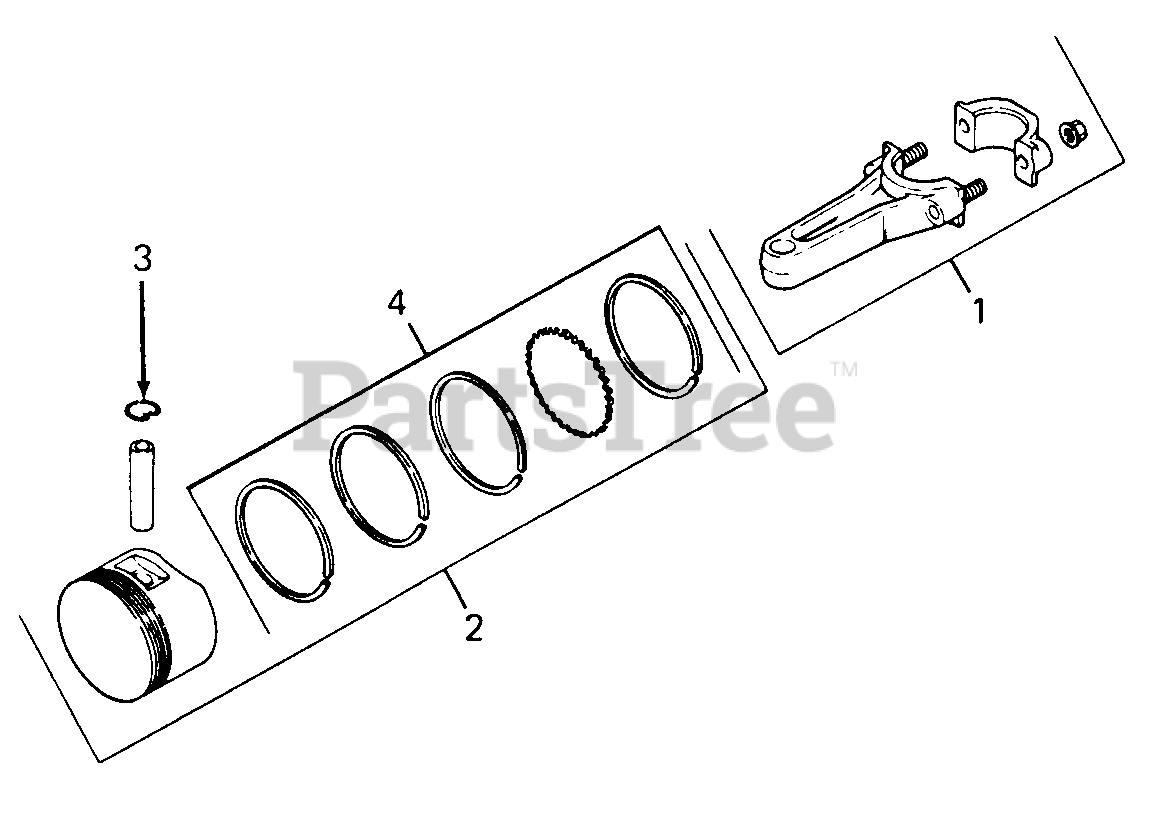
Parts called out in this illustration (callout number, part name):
1	Connecting Rod Assy, Std
2	Piston Assy, Std
3	Retainer, Piston Pin
4	Ring Set, Std .003
